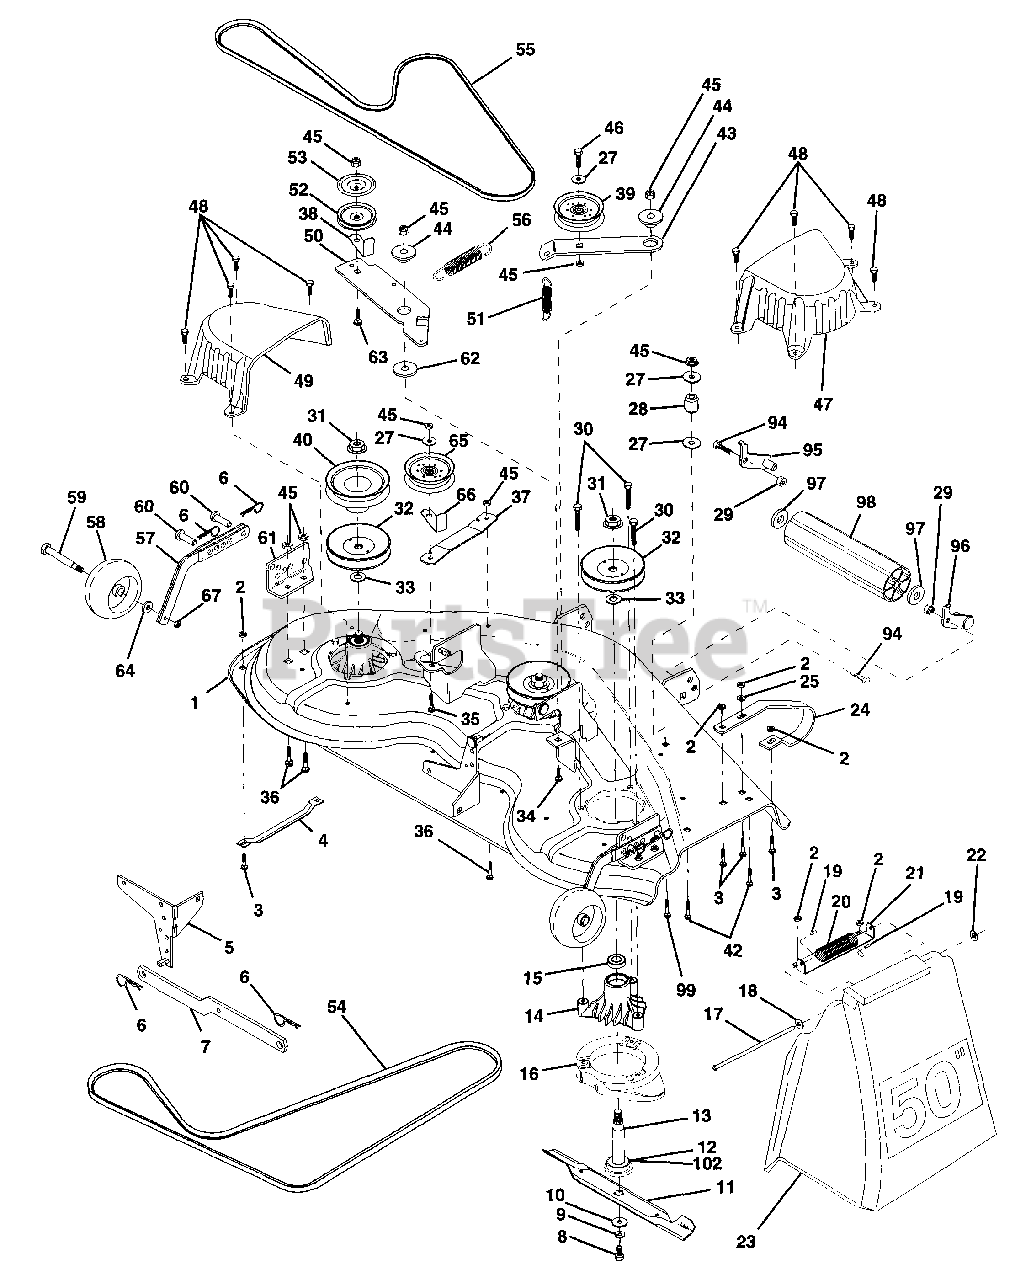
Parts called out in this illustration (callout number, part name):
1	Deck Asm., Mower 50" Vented
2	Nut, Crownlock 5/16-18 Unc
3	Bolt, Carriage 5/16-18 x 3/4
4	Runner, Mower LH
5	Bracket Asm., Sway Bar
6	Retainer, Spring
7	Arm Suspension, Rear
8	Bolt 3/8-24 x 1.25 Gr. 8 Patched
9	Washer, Lock Hvy 3/8 Unplated
10	Washer, Hard Blade Mower Vented
11	Blade (3 Required)
12	Bearing, Ball #6204 (Mandrel)
13	Shaft Asm., W/Lower Brg
14	Housing, Mandrel 50" Vent
15	Bearing, Ball Mandrel
16	Stripper, Mower Vented
17	Rod, Hinge
18	Washer 11/32 x 5/8 x 16 Ga.
19	Cap, Sleeve
20	Spring, Torsion Deflector
21	Bracket, Deflector
23	Shield, Deflector Mower
24	Runner, RH
25	Washer 11/32 x 3/4 x 16 Ga.
27	Washer 13/32 x 13/16 x 16 Ga.
28	Spacer, Spring Stop idler
29	Nut, Lock Hex W/Wsh 3/8-16 Unc
30	Screw Thdrol Hex Head
31	Nut, Flg Top Lock Cntr 9/16
32	Pulley, Mandrel
33	Washer, Spacer Mower Vented
34	Bolt, Carriage 3/8-16 x 1-1/4
35	Bolt, Carriage 3/8-16 x 2
36	Bolt, Carriage 3/8-16 x 1 Gr. 5
37	Stiffener, Arm Idler
38	Keeper, Belt Idler
39	Pulley, Idler Flat
40	Pulley, Driven
42	Bolt, Carriage 5/16-18 Unc x 3/4
43	Arm, Idler Secondary
44	Spacer, Retainer
45	Nut, Crownlock 3/8-16 Unc
46	Bolt, Fin Hex 3/8-16 Unc x 1-3/4
47	Cover, Mandrel RH
48	Screw, Thd Roll 1/4-20 x 5/8
49	Cover, Mandrel LH
50	Arm, Idler Primary
51	Spring, Secondary
52	Pulley, Idler V Groove
53	Shield, Idler
54	V-Belt, Mower Primary
55	V-Belt, Mower Secondary
56	Spring, Primary
57	Bar Asm., Wheel Gauge
58	Wheel, Gauge
59	Bolt, Shoulder
60	Pin, Clevis
61	Bracket, Wheel Gauge
62	Washer Hardened
63	Bolt Carriage 3/8-16 x 1-1/2
64	Washer 3/8 x 7/8 x 14 Ga.
65	Pulley Idler Flat Mower
66	Keeper, Belt Idler 50" Vent
67	Nut, Center Lock 3/8-16
94	Bolt, Fin Hex 3/8-16 UNC x 1
95	Bracket, Asm. Noseroller LH
96	Bracket, Asm. Noseroller RH
97	Washer 17/32 x 7/8 x 16 Ga.
98	Roller, Nose
99	Bolt, Carriage 3/8-16 x 1-3/4 Gr. S
102	Washer Felt
